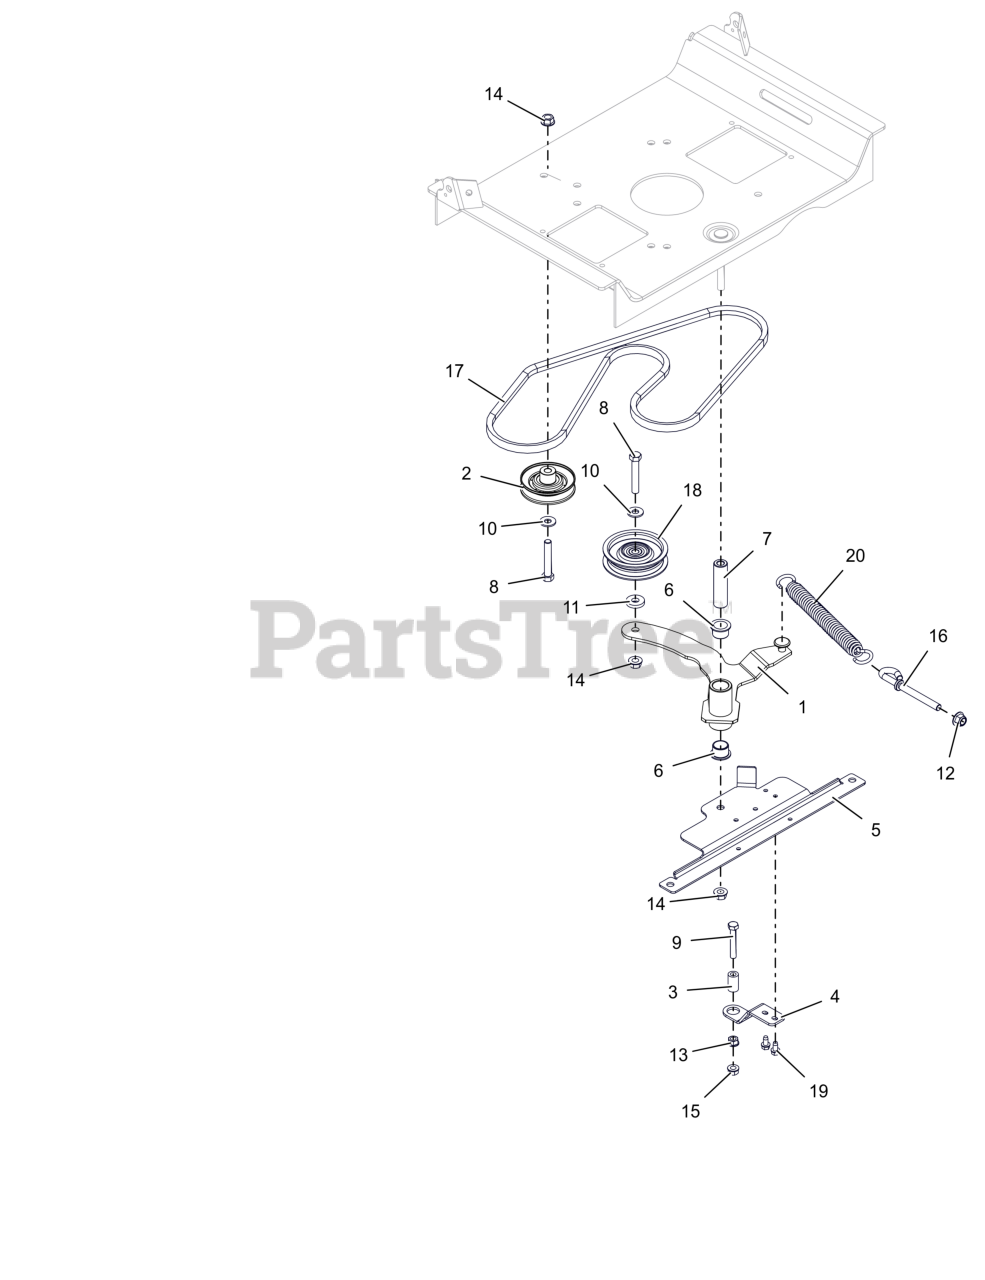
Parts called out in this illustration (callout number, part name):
1	WLDMT,GRD DRIVE IDLER ARM-LGR
2	IDLER, V-3.000 OD
3	SPACER, RUBBER 5/16 IDX1.0 LG
4	BRKT, CLUTCH STOP (XL)
5	BRKT-IDLER ATTACHMENT
6	BSHG-FLG 0.75X0.875X.625X1.125
7	BUSHING, SLEEVE .38X.750X2.78
8	BLT,HEX .38-16X2.25 G5 ZCC
9	BLT, HEX .31-18X2.00 G5 ZCC
10	WSHR,FLT .375X.875X.083 ZCC
11	WSHR, FLT .406X1.00X.188 ZCC
12	NUT,NYL-FLG .38-16 GF ZCC
13	NUT,SPNLK-FLG .31-18 G5 ZCC
14	NUT-LK-TOP-FLG .38-16 ZC120
15	NUT-LK-TOP-FLG .312-18 GF ZCC
16	BOLT- MODIFIED EYE-3/8-16UNC2A
17	V-BELT, A-RAW EDGE
18	SHEAVE, IDLER -V .38 x 4.00
19	SCR-TAP .25-20X.50 HWH ZCC
20	SPRING- EXTENSION
